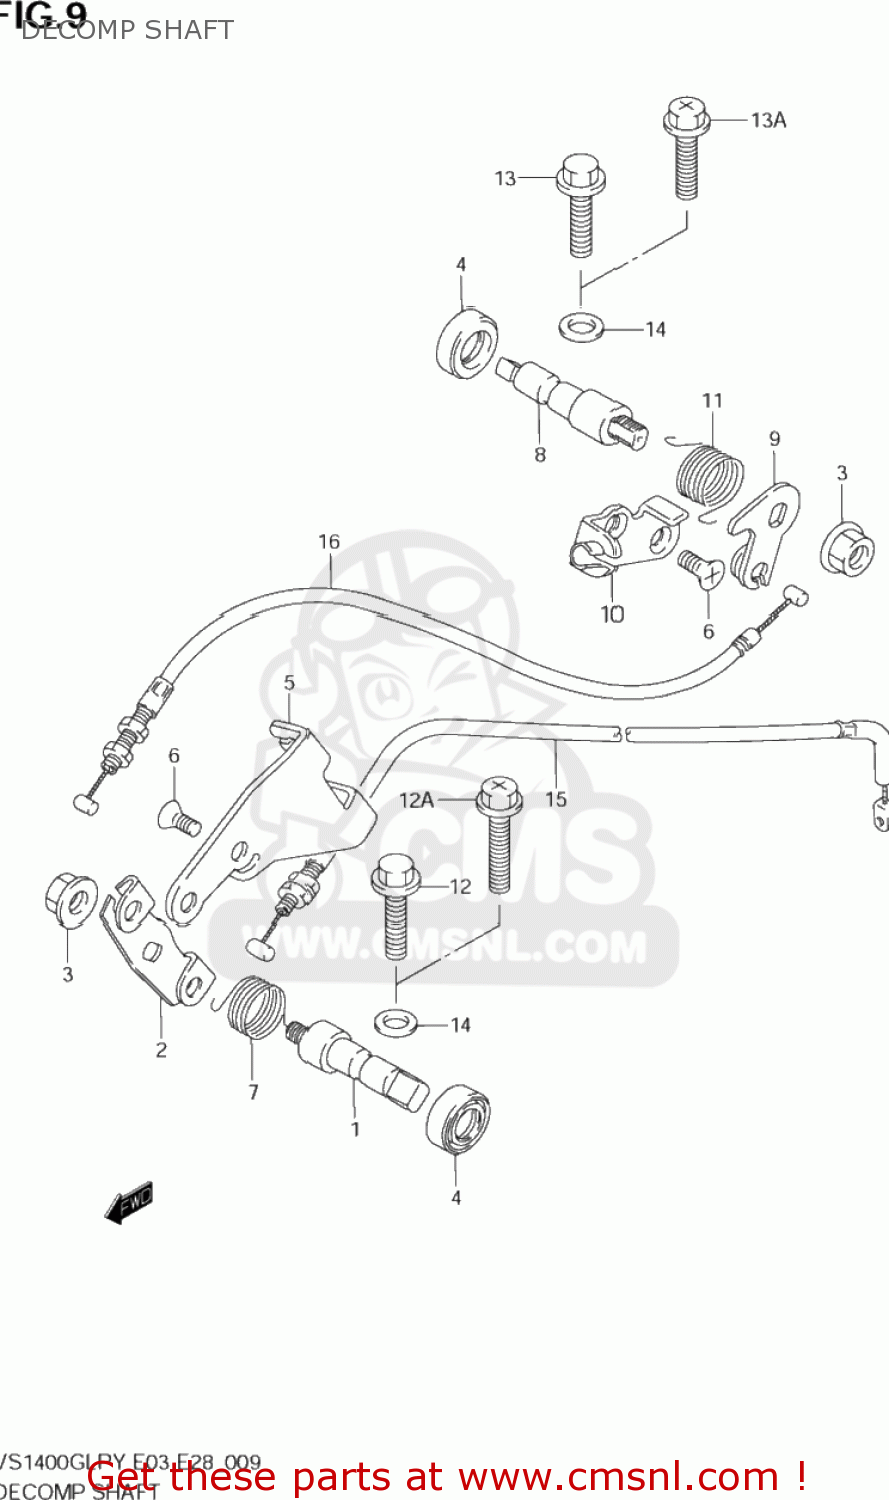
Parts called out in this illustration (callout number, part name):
1	SHAFT,DECOMP FR
2	LEVER,DECOMP SHAFT FR
3	NUT
4	SEAL,OIL(10X20X6)
5	HOLDER,DECOMP CABLE FR
6	SCREW
7	SPRING
8	SHAFT,DECOMP RR
9	LEVER,DECOMP SHAFT RR
10	HOLDER,DECOMP CABLE RR
11	SPRING
12	BOLT
12A	BOLT (GREEN)
13	BOLT
13A	SCREW
14	GASKET(5.8X13X1.2) (NAS)
15	CABLE ASSEMBLY,DECOMPRESSION
16	CABLE ASSEMBLY,DECOMPRESSION,REAR
